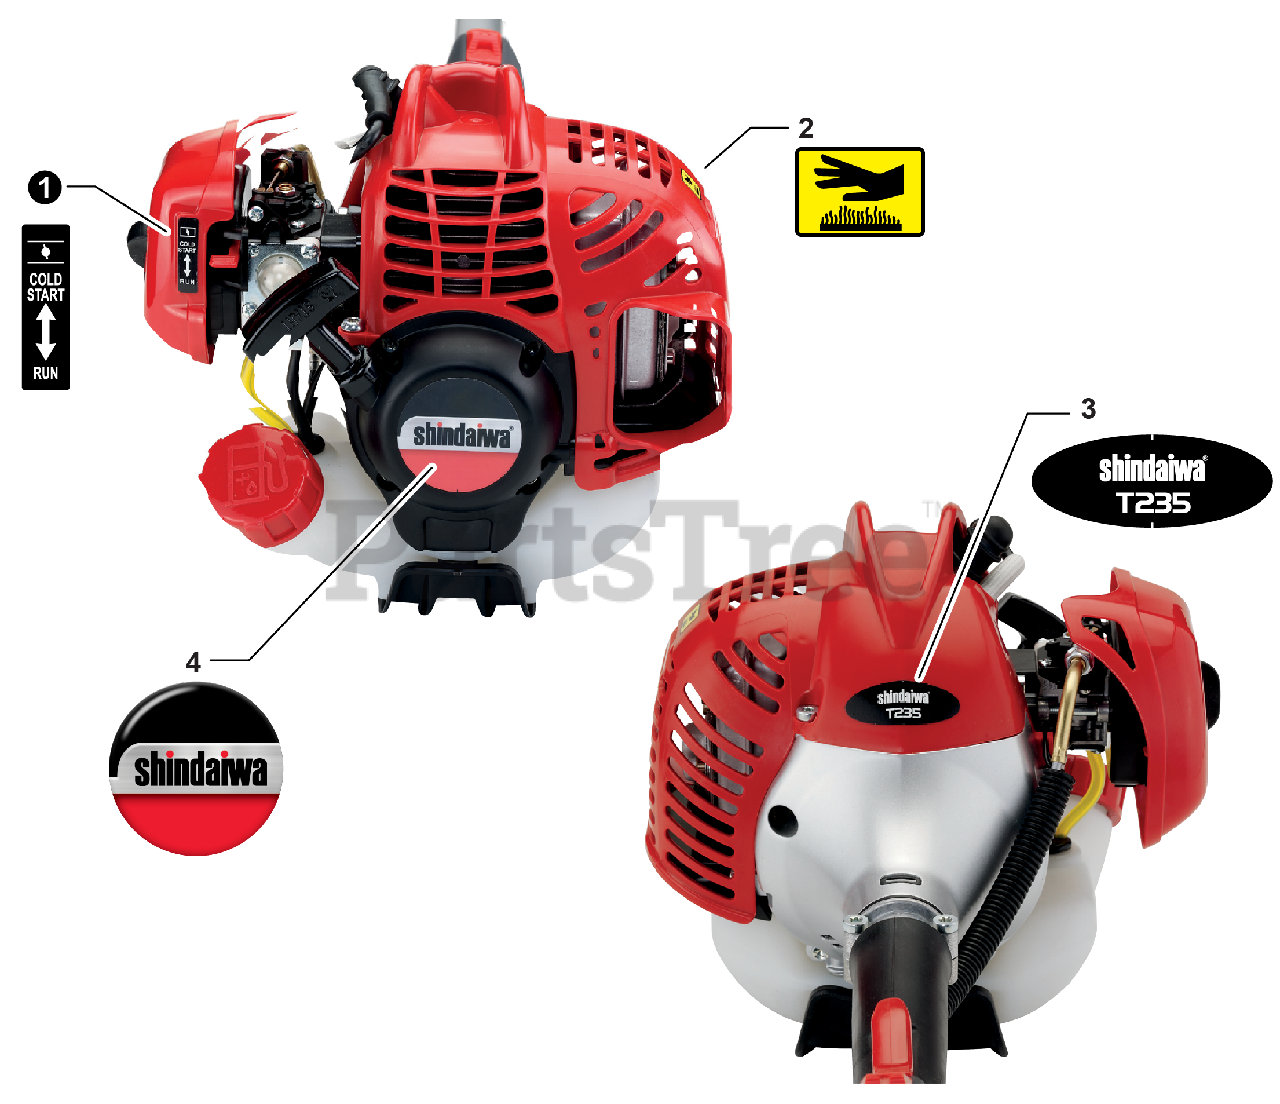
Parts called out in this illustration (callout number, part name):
1	LABEL, CHOKE
2	LABEL, CAUTION - HOT
3	LABEL - MODEL T235
4	LABEL, SHINDAIWA
